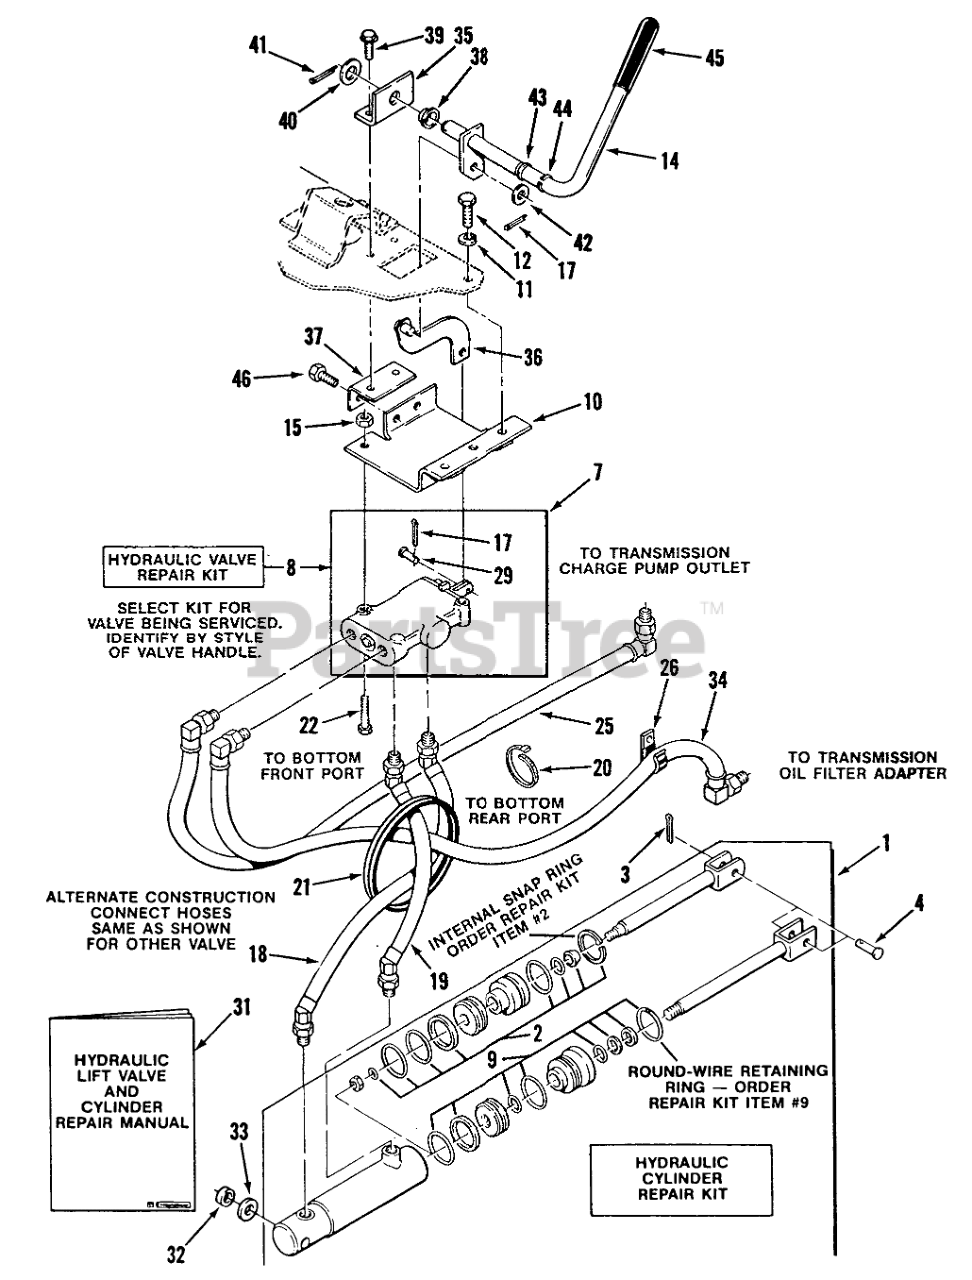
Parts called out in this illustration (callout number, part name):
1	CYLINDER
2	S/A O-RING&GASKET AS
4	CLEVIS PIN
7	ASS'Y-VALVE
8	S/A 110068 VALVE
9	S/A 108872 HYD CYL
10	ASS'Y-VALVE SUPPO B
11	Lockwasher
12	Bolt
14	ASSY-LEVER LIFT
15	Nut
17	Cotter Pin
18	Hose ASM-Hydraulic
19	Hose ASM-Hydraulic
20	PLASTIC TIE
21	GROMMET
22	Bolt 1/4-20 x 2
25	ASSY HOSE HYDRAULIC
26	CLIP
29	Pin
31	Repair Manual
32	Spacer
33	WASHER
34	ASSY HYD HOSE
35	SUPPORT-LEVER ASS B
36	ASS'Y-BAR LIFT B
37	BRACKET-SUPPORT B
38	NYLINER BUSHING
39	Bolt
40	SHIM-WASHER
41	Pop Rivet
43	BUSHING-NYLINER
44	Grip Ring
45	GRIP
46	Bolt
